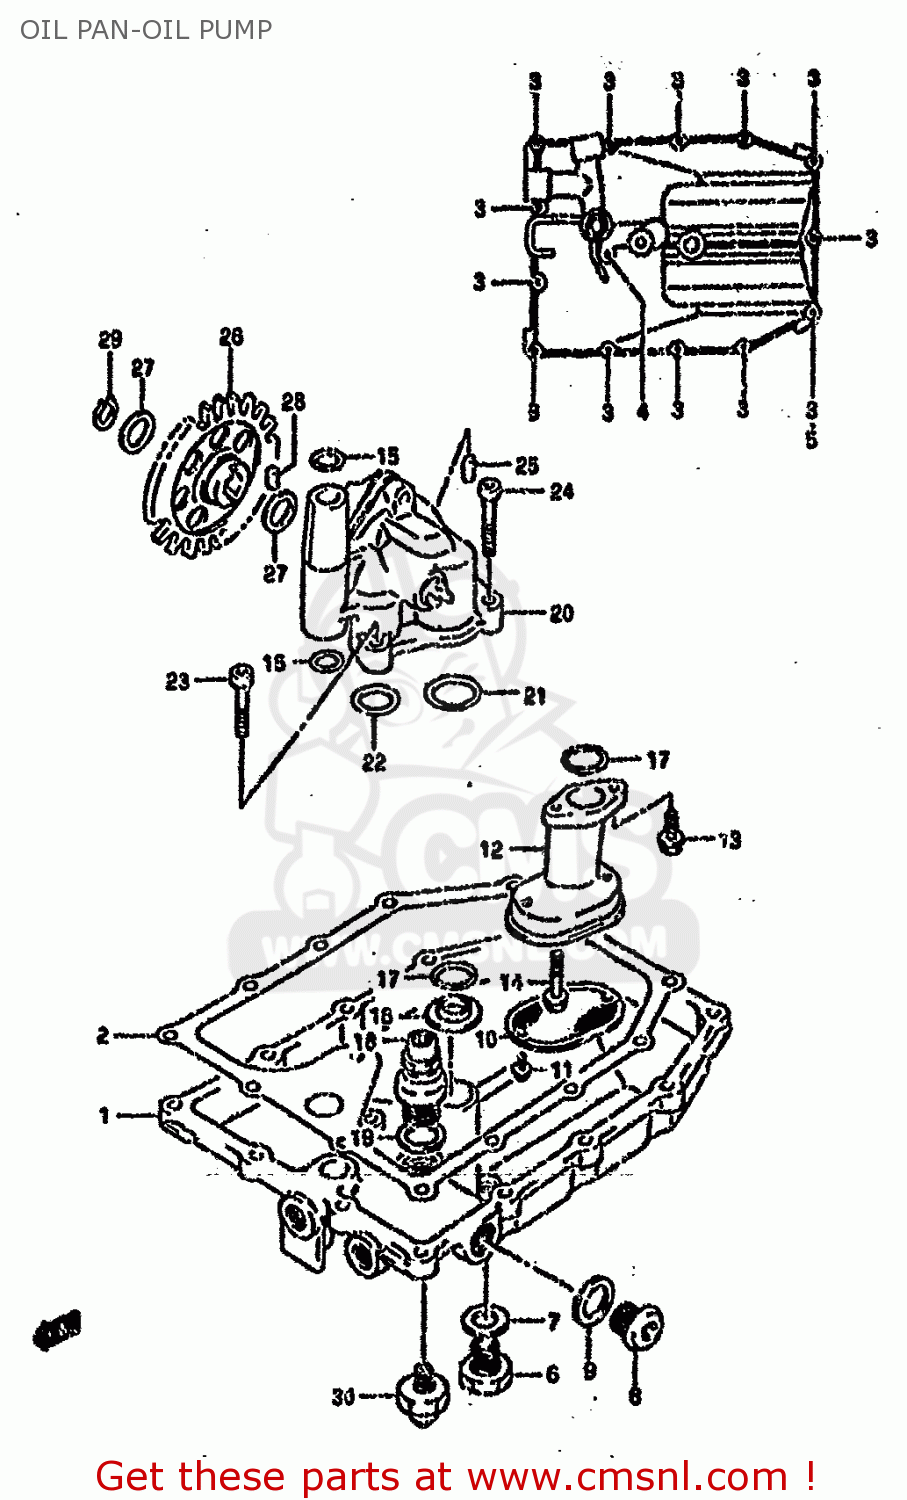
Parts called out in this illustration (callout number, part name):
1	PAN,OIL
2	GASKET,OIL PAN (NAS)
3	SCREW
4	BOLT
5	GASKET(5.8X11X1.2) (NAS)
6	PLUG
7	GASKET(13.8X18.8X4.8) (NAS)
8	PLUG
9	GASKET(16X22X2) (NAS)
10	STRAINER,ENGINE OIL
11	SCREW
12	PROTECTOR,OIL STRAINER
13	BOLT
14	BOLT, HYDRAULIC UNIT NO.2
15	O RING(D:2.4,ID:11.8)
16	GASKET,OIL OUTLET (NAS)
17	O RING(D:3.2,ID:17.8)
18	VALVE ASSEMBLY,OIL RELIEF
19	GASKET(16X22X2) (NAS)
20	PUMP ASSY,ENGINE OIL
21	O RING(D:2.4,ID:26.2)
22	O RING(D:3.2,ID:17.8)
23	BOLT
24	BOLT
25	PIN
26	GEAR,OIL PUMP DRIVEN(NT:37)
27	SHIM
28	PIN(5X18)
29	CIRCLIP,12 MM
30	SWITCH ASSEMBLY,OIL PRESSURE
